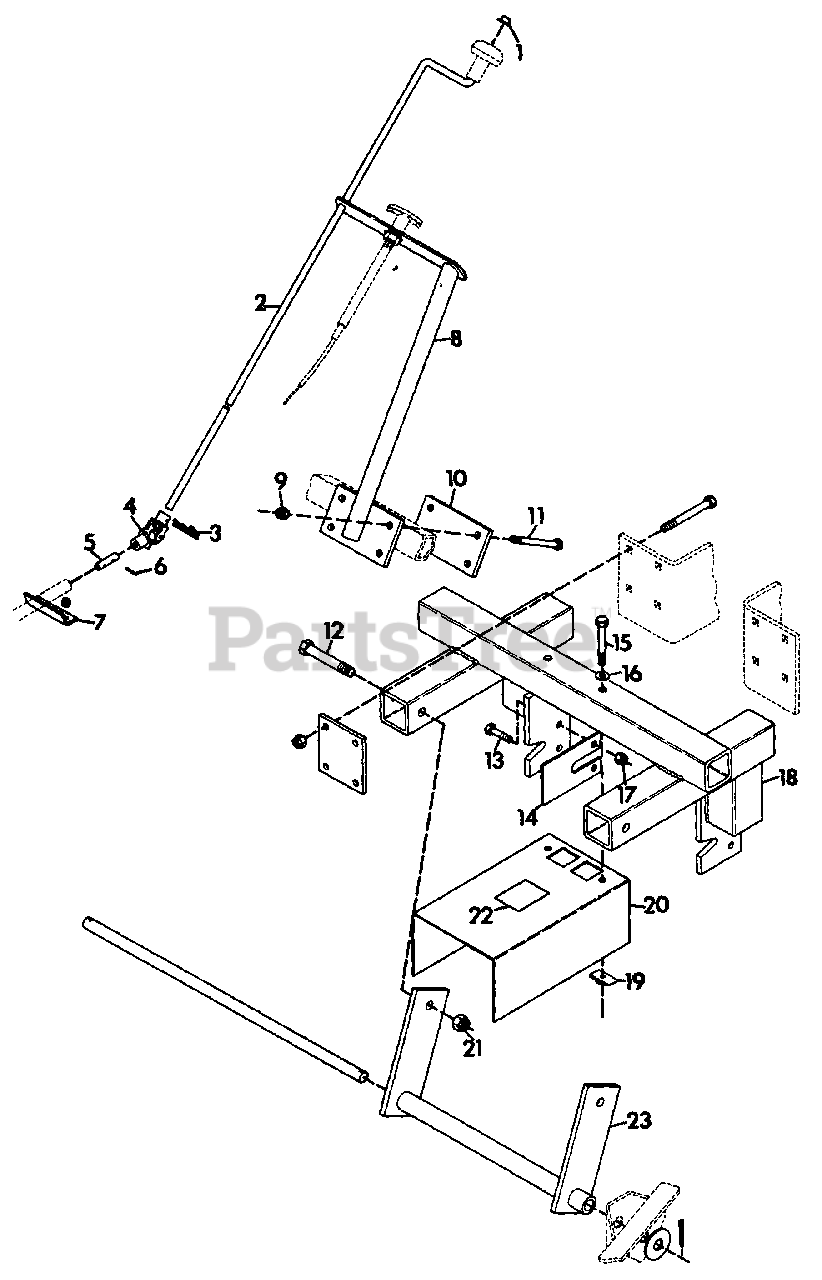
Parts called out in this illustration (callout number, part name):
1	CAP
2	CONTROL, CRANK CHUTE
3	HAIR PIN, INTERNAL
4	ASSEMBLY, U-JOINT
5	ADAPTER, U-JOINT
6	PIN, SPRING .125X.750
7	BRACKET
8	WELDMENT, CRANK SUPPORT
9	NUT, LOCK 3/8-16 HEX
10	PLATE, CHANNEL CLAMP
11	BOLT, HEX 3/8-16X2.50
12	BOLT, HEX 1/2-13X3.00
13	BOLT, HEX 5/16-18X1.00
14	PLATE, CLAMP
15	BOLT, HEX 5/16-18X2.75 GR. 8
16	WASHER, LOCK 5/16 REG.
17	NUT, LOCK 5/16-18 HEX
18	WELDMENT, FRAME MOUNT
19	RETAINER, NUT
20	GUARD, PTO
21	NUT, LOCK 1/2-13
22	DECAL, DANGER HAND
23	WELDMENT, HITCH
NS	DECAL, CHUTE CHRANK
NS	V-BELT
NS	SHEAVE
NS	SHAFT, PROP. SQ. BAR
